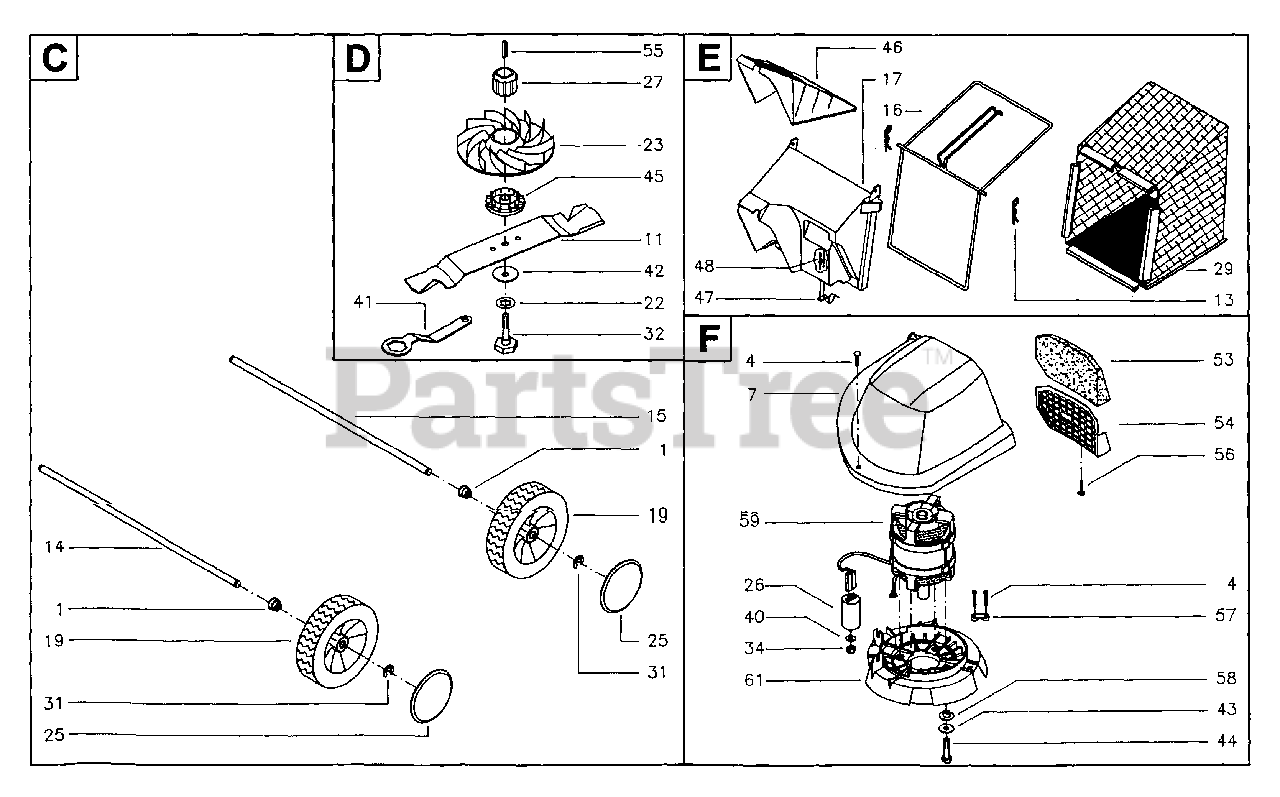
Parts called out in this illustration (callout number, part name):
1	CONE SPRING
23	IMPELLER
26	CAPACITOR
31	SNAP RING
34	NUT
40	WASHER - 15X7.3X1.6
42	DISC SPRING
57	CABLE CLAMP
58	FLANGE BRG.
